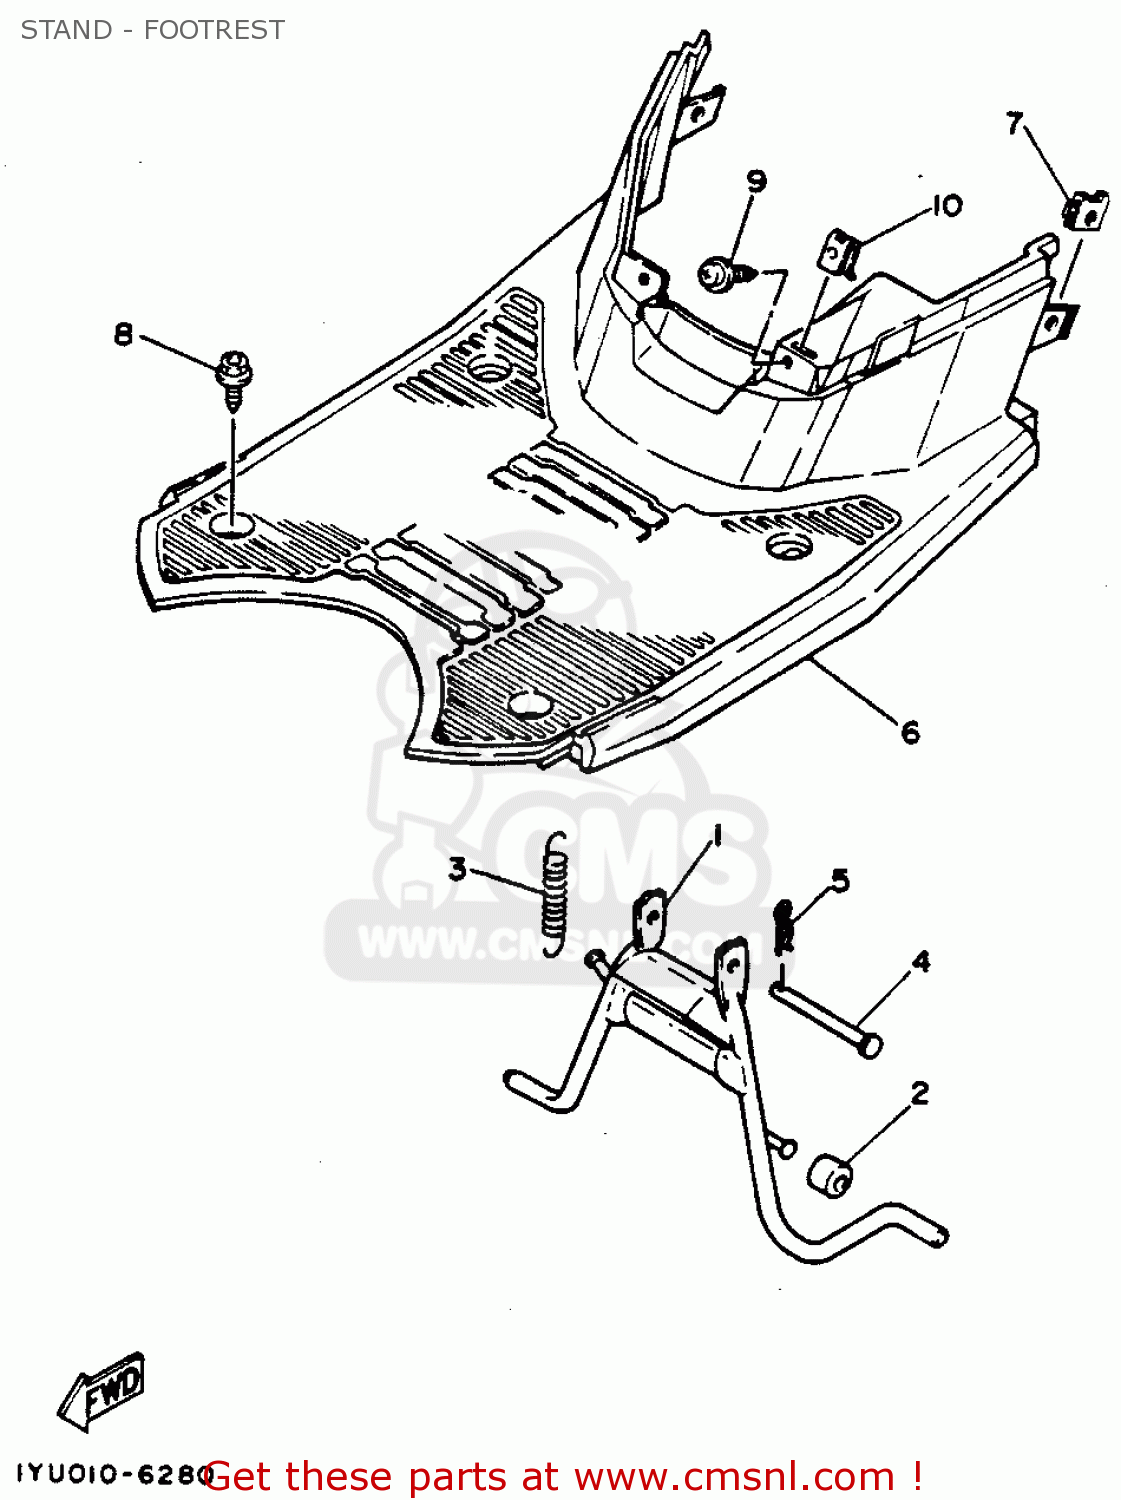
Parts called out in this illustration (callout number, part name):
1	STAND, MAIN
2	COLLAR (3V6)
3	SPRING
4	PIN, CLEVIS(1YU)
5	CLIP 136253750000
6	BOARD, FOOTREST
7	NUT 1
8	BOLT, WITH WASHER (14T)
9	SCREW, WITH WASHER (35R)
10	NUT, SPRING (2E9)
